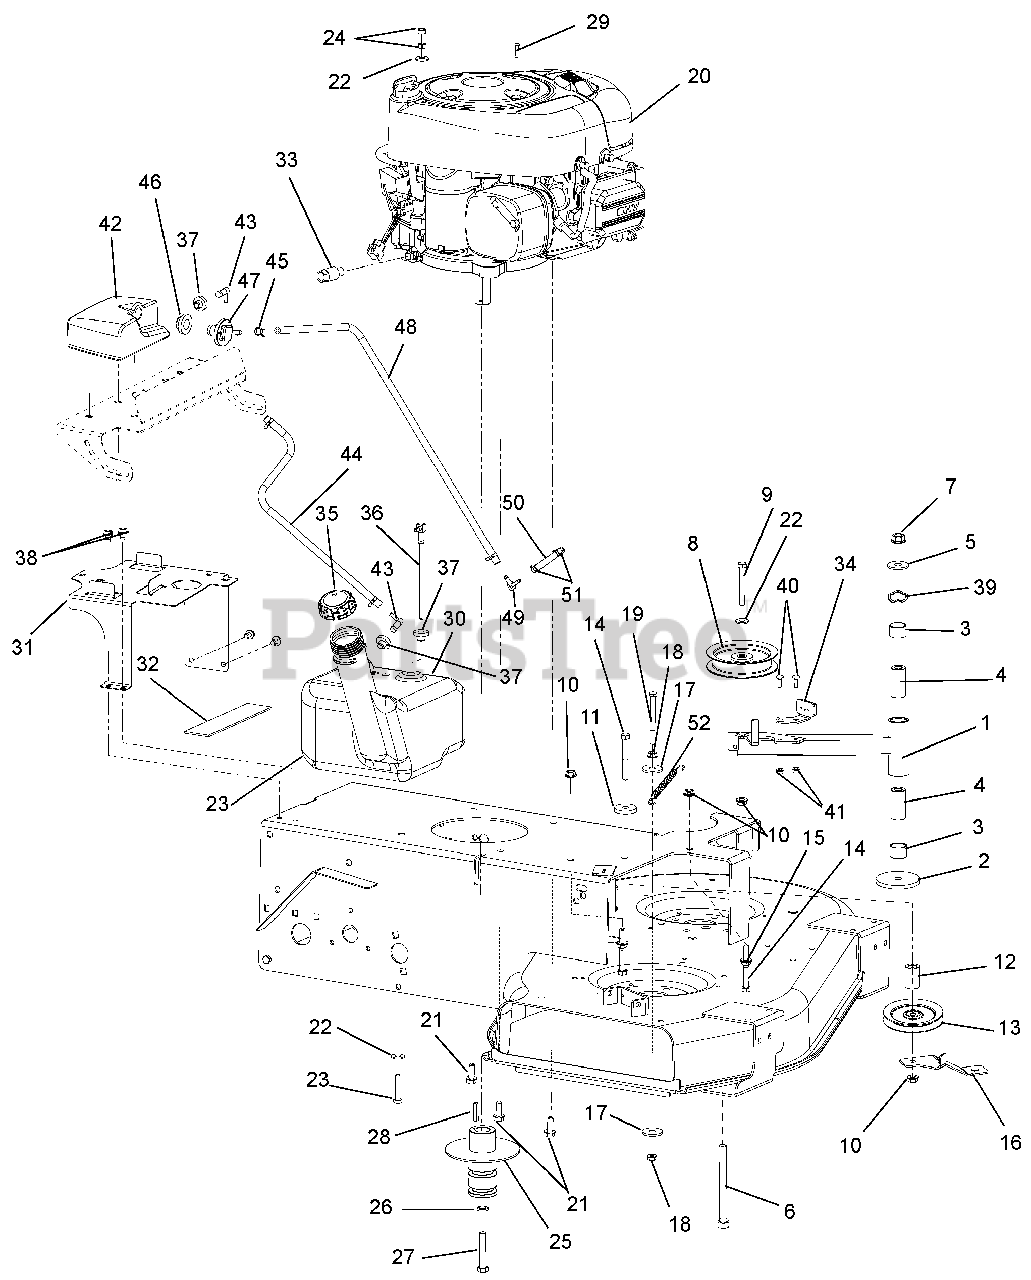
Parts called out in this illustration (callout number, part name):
1	WLDMT, PTO IDLER ARM
2	WASHER, FLAT .531X3.000X.25
3	BRG, 1.00 X 1.12 X .75
4	BSHG, SPCR .502X.997X2.03 PM
5	WSHR-FL-STL.511X1.441X.125 YWZ
6	@BLT-HEX .50-13X5.50 GR5YWZC
7	@NUT-LK-TOP-FLG .50-13 YWZC
8	ASM, IDLER 4"
9	@BLT-HEX .38-16X2.75 GR5 YWZC
10	@NUT-LK-TOP-FLG .38-16 YWZC
11	WSHR,FLT STL.406X1.50X.245YWZC
12	SPACER, .437X1.0X1.23
13	SHV, .38"ID X 4.00"OD V-IDLER
14	@BLT-HEX .38-16X3.00 GR5 YWZC
15	@NUT-SPNLK-FLG .375-16 YWZC
16	BRKT-IDLER BRACE
17	WSHR-FL-STL .406X1.375X.135 YZ
18	@NUT-SPNLK-FLG .312-18 YWZC
19	@BLT-HEX .31-18X3.50 GR5 YWZC
20	ENGINE, B&S 14.5 POWERBUILT
21	@SCR-TAP .38-16X1.00 HWH TR YZ
22	@WSHR-FL-STL.38X.875X.083 YWZC
23	@BLT-HEX .31-18X1.75 GR5 YWZC
24	@NUT-LK-CTR .31-18 YWZC
25	PULLEY, PRO-GROUND DRIVE
26	@WSHR-LK .44X.109 REG YWZC
27	BLT-HEX .44-20X2.50 G5 YZ EP80
28	KEY-SQ .25 X 1.25 X .25 SAE
30	TANK, ZOOM/WAW NON-PERM. FUEL
31	BRKT, GAS TANK MOUNT
32	PAD, GAS TANK
33	DRAIN, OIL
34	BRAKE PAD ASSY WAW
35	CAP, 2.25" ONE-WAY VENT FUEL
36	ASSY-PICKUP, FUEL 6.5L
37	BSHG-FLG .375X1.062X.625 NITR
38	@SCR-TAP .31-18X.50 HWH TR YWZ
39	WASHER - WAVE 1.09X1.37X.016
40	@BLT-RDHDSQNK .25-20X.75 G5YZ
41	@NUT-LK-TOP-FLG .25-20 YWZC
42	TANK, FUEL EXPANSION
43	FITTING, STRAIGHT FUEL PLASTIC
44	HOSE, .25 LOW-PERM BULK GAS
45	CLAMP-HOSE WIRE .490/.510X.116
46	GROMMET, REMOTE VENT NITRILE
47	VENT, ROLL-OVER (.25"ID HOSE)
48	HOSE, .25 LOW-PERM BULK GAS
49	FITTING-3/16X1/4 90DEGREE VAC
50	HOSE, .188 LOW-PERM BULK GAS
51	CLAMP-HOSE, SPRING .188
52	SPRING - ENGINE - TRANS.
